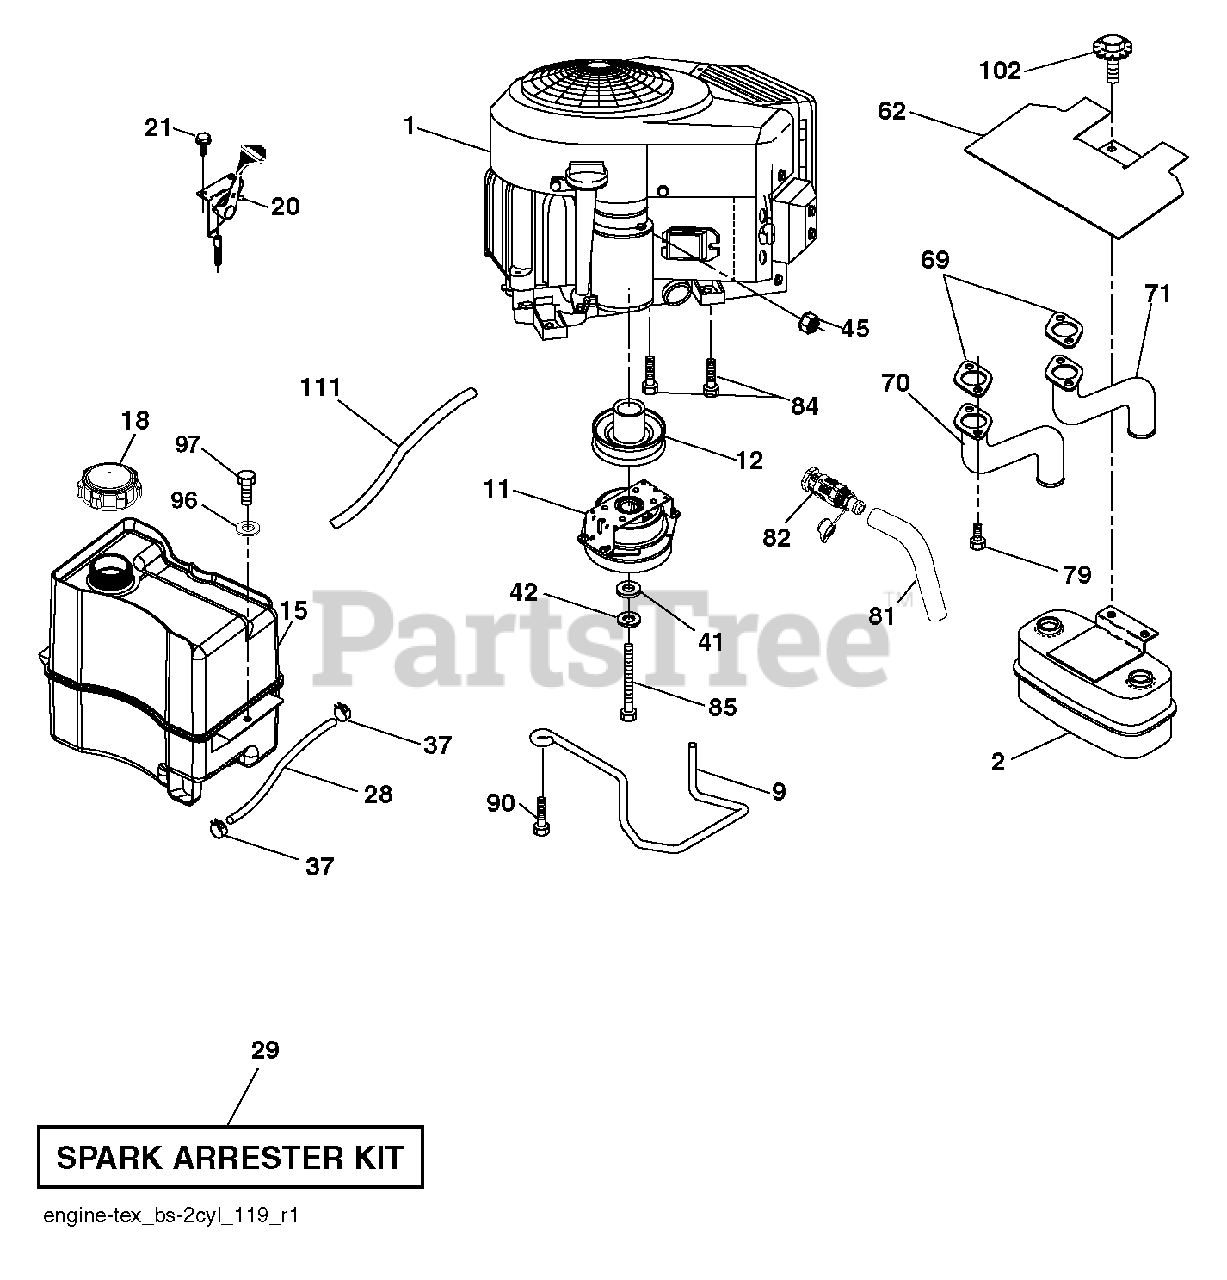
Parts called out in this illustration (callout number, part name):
2	MUFFLER.ASM.TWN.EXTNDED.DFLCTR
9	KEEPER.BELT.ENGINE
11	Clutch, Ogura 5.0Pd Gt1.5A-Eh07
12	PULLEY.ENGINE.ENX
15	TANK.ASM.FRT.2.5 GAL.W/CAP.EPA
18	CAP.FUEL.2 WAY VENT
20	Throttle, Cobra 38" Readstart.Bk
21	SCREW.#10 X 0.750.BOS (2 2)
28	LINE.FUEL.20"FRONT.EMI
29	SPARK ARRESTOR KIT
37	HOSE CLAMP
42	LOCKWASHER
45	NUT
62	SHIELD.HEAT.MUFFLER
69	GASKET.MUFFLER
70	EXHAUST.TUBE.LH.BS/TWIN
71	EXHAUST.TUBE.RH.B&S.TWIN.INTEK
79	SCREW.SOCKET.HEAD.5/16-18
81	TUBE, DRAIN OIL ASM.
82	VALUE.OIL.DRAIN
84	SCREW.3/8-16
85	Hex Bolt, 7/16-20 X 3.75 Gr5 Red
90	SCREW 3/8-16X1
97	SCREW HEXWSHR 1/4-20X3/4
102	SCREW
111	RP PURGE LINE
